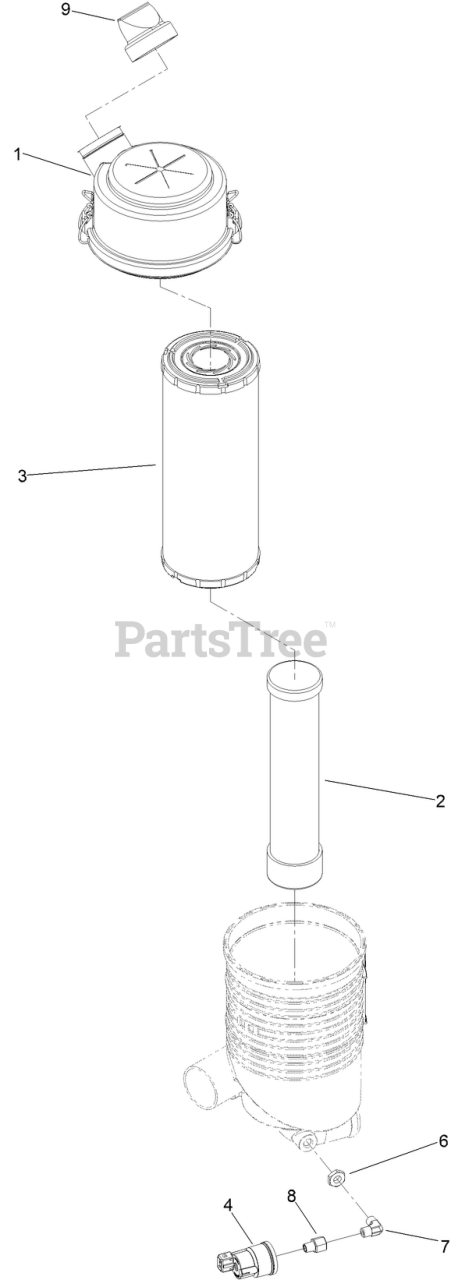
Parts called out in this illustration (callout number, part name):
1	COVER ASM
2	FILTER-AIR, SAFETY
3	FILTER-AIR
4	INDICATOR-MINI
6	NUT-HEX
7	FITTING-ELBOW-90
8	INSERT-RESTRICTION ADAPTER
9	VALVE-DUST-AIR CLEANER
